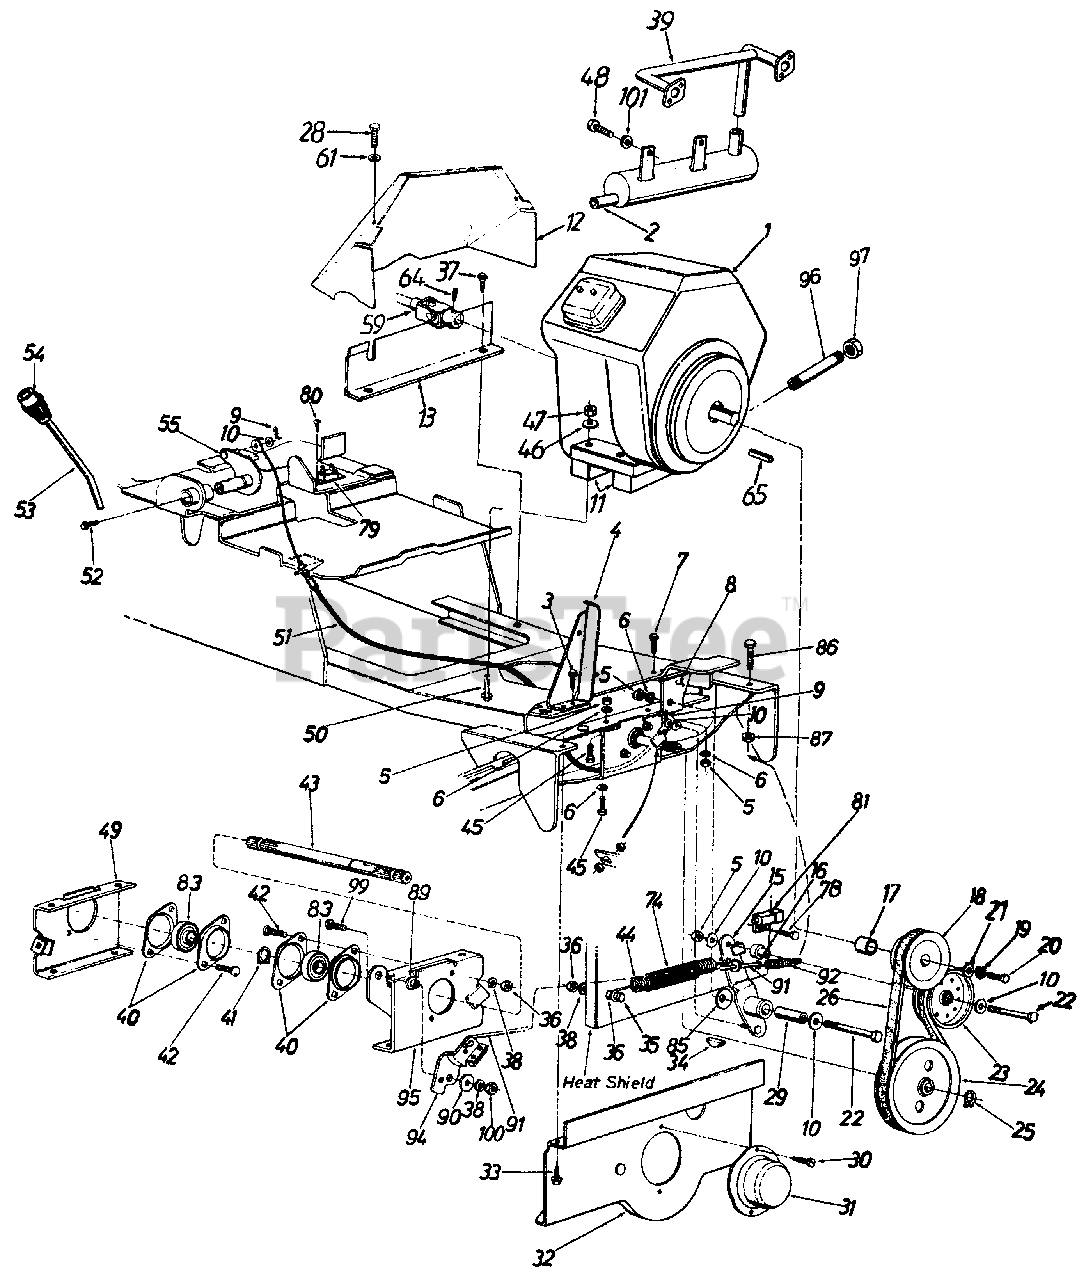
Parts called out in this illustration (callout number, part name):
1	Engine (Kohler)
2	Muffler
3	Hex Wash. Hd. Self-Tap Scr. 1/4-20 x .75"
6	L-Wash. 3/8" I.D.
7	Hex Wash. Hd. Self-Tap Scr. 5/16-18 x .75" Lg.
10	Fl-Wash. .38" I.D. x 1.25" O.D. x .100" Thk.
11	Engine Mounting Spacer
12	Heat Shield
13	Heat Baffle-Lower
17	Pulley Spacer
18	Engine PTO-Pulley
19	L-Wash. 3/8" I.D.
20	Hex Bolt 3/8-16 x 1" Lg.
21	Fl-Wash. 3/8" I.D. x 1.37" O.D.
22	Hex Bolt 3/8-16 x 2.50" Lg.
23	Flat Idler Pulley
24	1/2" V-Pulley 7.00" O.D. (PTO)
25	Snap Ring
26	V-Belt (PTO)
28	Hex Bolt M6-1.0 x 10mm Lg.
29	Spacer .375" I.D. x .62" O.D. x 1.830" Lg.
30	Hex B Tap Scr. #10 x .50" Lg.
34	#91 Hi-Pro Key
35	Hex Bolt 5/16-18 x 1.25" Lg.
36	Hex Nut 5/16-18 Thd.
37	Hex Wash. Hd. Tap Scr. 5/16-18 x .5" Lg.
38	L-Wash. 5/16" I.D.
39	Exhaust Pipe
40	1.00" Dia. Brg. w/Flangette
41	Snap Ring
42	Carr. Bolt 5/16-18 x .75" Lg.
43	Spline Shaft
44	Extension Spring (PTO Clutch)
45	Hex Bolt 3/8-16 x 1" Lg.
46	L-Wash. 3/8" I.D.
47	Hex Nut 3/8-16 Thd.
48	Hex Bolt 7/16-14 x 1" Lg.
49	PTO Bearing Retainer Brkt.
50	Hex Bolt 3/8-16 x 2.25" Lg.
51	PTO Control Cable
52	Hex TT-Tap Scr. 1/4-20 x .5" Lg.
53	PTO Handle
54	Shift Knob
55	PTO Actuator Lever Assembly
59	Universal Drive Shaft Comp.
61	Fl-Wash. .281" I.D. x .5" O.D.
64	Set Scr. 5/16-18 x .38" Lg.
65	Sq. Key 1/4" x 2" Lg.
74	Spring Cover Tubing (PTO Clutch)
78	Hex Bolt 1/4-20 x 1/2" Lg.
79	Circuit Breaker
80	Truss Mach. Scr. #10 x .50" Lg.
81	Safety Switch (PTO)
83	Ball Bearing
85	Bell-Wash. .39" I.D. x 1.13"
86	Hex Bolt 3/8-16 x 1.5" Lg.
87	Hex L-Nut 3/8-16 Thd.
89	Shoulder Spacer
90	Fl-Wash. .33" I.D. x 1.25" O.D.
91	PTO Brake Rod
92	Extension Spring 2.15" Lg.
94	Brake Assembly
95	PTO Brg. Retainer Brkt. Assembly
96	Pipe Nipple 3/8" x 5" Lg.
97	Oil Drain Cap
99	Hex Bolt 5/16-24 x .75" Lg.
100	Hex Nut 5/16-24 Thd.
101	L-Wash. 7/16" I.D.
